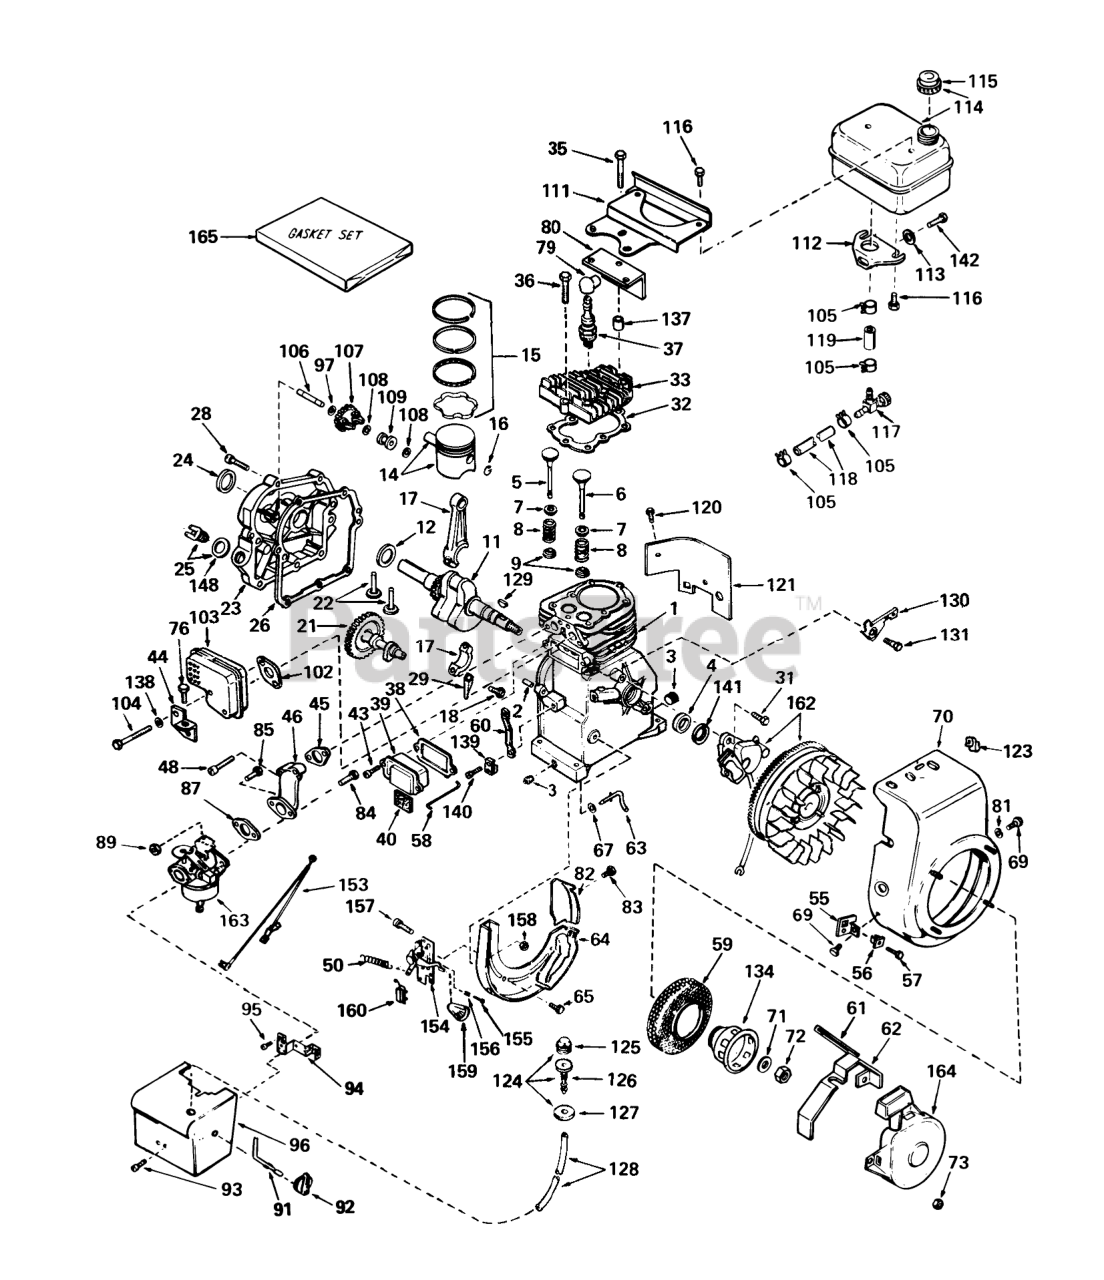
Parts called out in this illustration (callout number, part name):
1	Cylinder Assy. (Incl. #2, 3 4)
2	Pin-Dowel
3	Plug-Drain, Oil (SQH 1/4-18)
4	Seal-Oil
5	Valve, Intake (Standard) (Incl. Nos. 7, 9 10)
5	Valve, Intake (1/32" Oversize) (Incl. Nos. 7, 9 10)
6	Valve, Exhaust (Standard) (Incl. Nos. 8, 9 10)
6	Valve, Exhaust (1/32" Oversize) (Incl. Nos. 8, 9 10)
7	Cap-Upper Valve Spring
8	Spring-Valve
9	Cap-Valve, Spring
11	Crankshaft Assembly
12	Washer-Thrust
14	Piston Pin Assy. (Incl . Ref. . #14) (Std.)
14	Piston, Pin Ring Assy. (Std.)(Incl. Ref. #13A, 14 15)
14	Piston Pin Assy. (Incl. Ref. #14) (.010 Oversize)
14	Piston,Pin Ring Assy. (.010 over-size)(Incl. Ref. #13A, 14 15)
14	Piston Pin Assy. (.020 oversize) (Incl. Ref. #14)
14	Piston, Pin Ring Assy. (Incl. Nos. 13A, 14 15)(.020 oversize)
15	Ring Set Piston (Std.)
15	Ring Set Piston (.010 Oversize)
15	Ring Set Piston (.020 Oversize)
16	Ring-Retaining, Piston Pin
17	Rod Assembly, Connecting (Incl. Nos. 17 18)
18	Bolt-Rod, Connecting
21	Camshaft
22	Lifter-Valve
23	Cover, Cylinder (Incl. Nos. 24, 25, 106 148)
24	Seal-Oil
25	Plug-Fill, Oil
26	Grommet 2 1/2 Dia.
28	Screw
29	Dipper-Oil
31	Screw
32	63573 GIL 42 SNWTHW
33	Head Cylinder
35	Screw (5/16-18 X 2)
36	Screw (5/16-18x1-1/2)
37	Plug, Spark (J17LM or equiv.)
37	Plug, Spark (Champion RCJ-8)
38	Gasket Breather
39	Breather Assembly (Incl. Nos. 52 84)
40	Element-Breather
43	Screw
44	Bracket-Cover, Carburetor
45	Gasket, Intake
46	Pipe, Intake
48	Screw (1/4-20 x 1-19/32)
50	Spring-Extension
55	Bracket
56	Grommet
57	Screw
58	Link-Governor to Throttle
59	Screen-Starter
60	Lever, Governor
61	Seal, Snowguard
62	Guard-Starter
63	Rod-Governor
64	Baffle-Blower Housing
65	Screw (1/4-20x19/32)
67	Washer-Flat
69	Screw
70	Housing, Blower
71	Washer-Spring
72	Hex Nut
73	Nut and Lock Washer (1/4-28)
76	Screw (10-24 x 3/8)
79	Cover-Spark Plug
80	Baffle-Heat
81	Washer
82	Baffle-Extension
83	Screw-Hex Washer Hd.
85	Screw-Fil. Hd.
87	Gasket
89	Nut and Lock Washer (1/4-28)
91	Rod-Choke
92	Knob-Control
93	Screw (8-32 X 5/16)
94	Bracket-Choke
95	Screw (10-32 x 1/2)
96	Cover, Carburetor
97	Washer-Flat
102	Gasket-Intake
103	Muffler
104	Screw-Fil. Hd.
105	Clamp-Line, Fuel
106	Shaft-Governor
107	Governor Gear ASM
108	Ring-Retaining
109	Spool, Governor
111	Plate-Fuel Tank
112	Bracket, Fuel Tank Lower
113	Washer
114	53023/VAR.10/16HP O
115	Cap, Fuel
116	Screw (1/4-15x7/8)
117	Valve-Shut Off
118	Line-Fuel
119	Line-Fuel (8.62)
120	Screw
121	Extension-Blower
123	51004 GIL ROTARY TI
124	Primer Assy. (Incl. Nos. 89, 90 91)
125	Bulb, Primer
126	Body, Primer
127	Retainer, Primer Bulb
128	Line, Primer
129	Key, FIywheel
130	Bracket-Hold Down
131	Screw (10-24 x 9/16)
134	Cup, Starter
137	pacer
138	Washer
139	Clamp-Lever, Governor
140	Screw
141	Gasket Stator
142	Screw Assembly
148	Gasket
153	Wire-Ground
154	Control Assembly, Speed (Incl. Ref. #155 thru 158 160)
155	Screw
156	Spring-Compression
157	Screw
158	Nut-Lock
159	Knob-Control
160	Terminal
162	Magneto
163	Carburetor (Incl. Ref. #87)
164	Starter Assy., Rewind
165	Gasket
